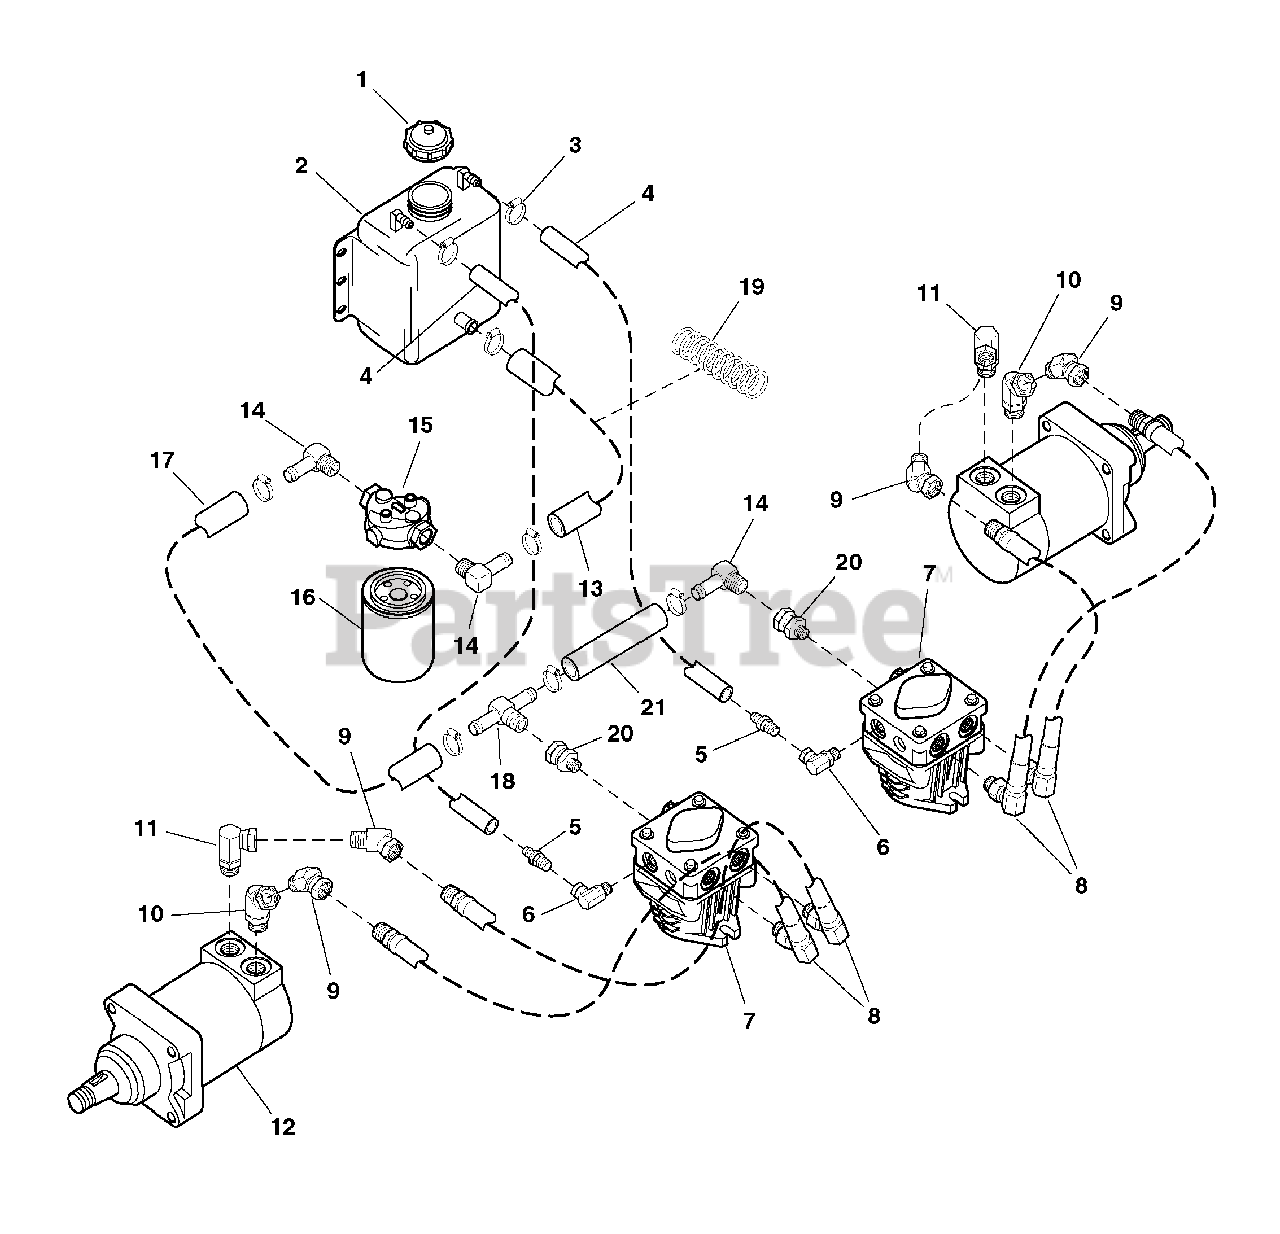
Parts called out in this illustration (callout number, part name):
4	HOSE, Return
5	FITTING, Hose, Straight
6	FITTING, Hydraulic, 90 Deg. O-Ring Swivel
7	HYDRAULIC PUMP
9	FITTING, Hydraulic, 45 Deg. Swivel
10	FITTING, Hydraulic, 45 Deg. O-Ring Swivel
11	FITTING, Hydraulic, 90 Deg. O-Ring Swivel
12	HYDRAULIC WHEEL MOTOR
13	HOSE, Supply (Tank to Filter)
14	FITTING, Hose, 90 Deg.
15	FILTER HEAD
16	HYDRAULIC FILTER
17	HOSE, Supply (Filter to LH Pump)
18	FITTING, Hose Tee
19	SPRING, Compression
20	FITTING, Hydraulic, Straight Swivel
21	HOSE, Supply (LH Pump to RH Pump)
